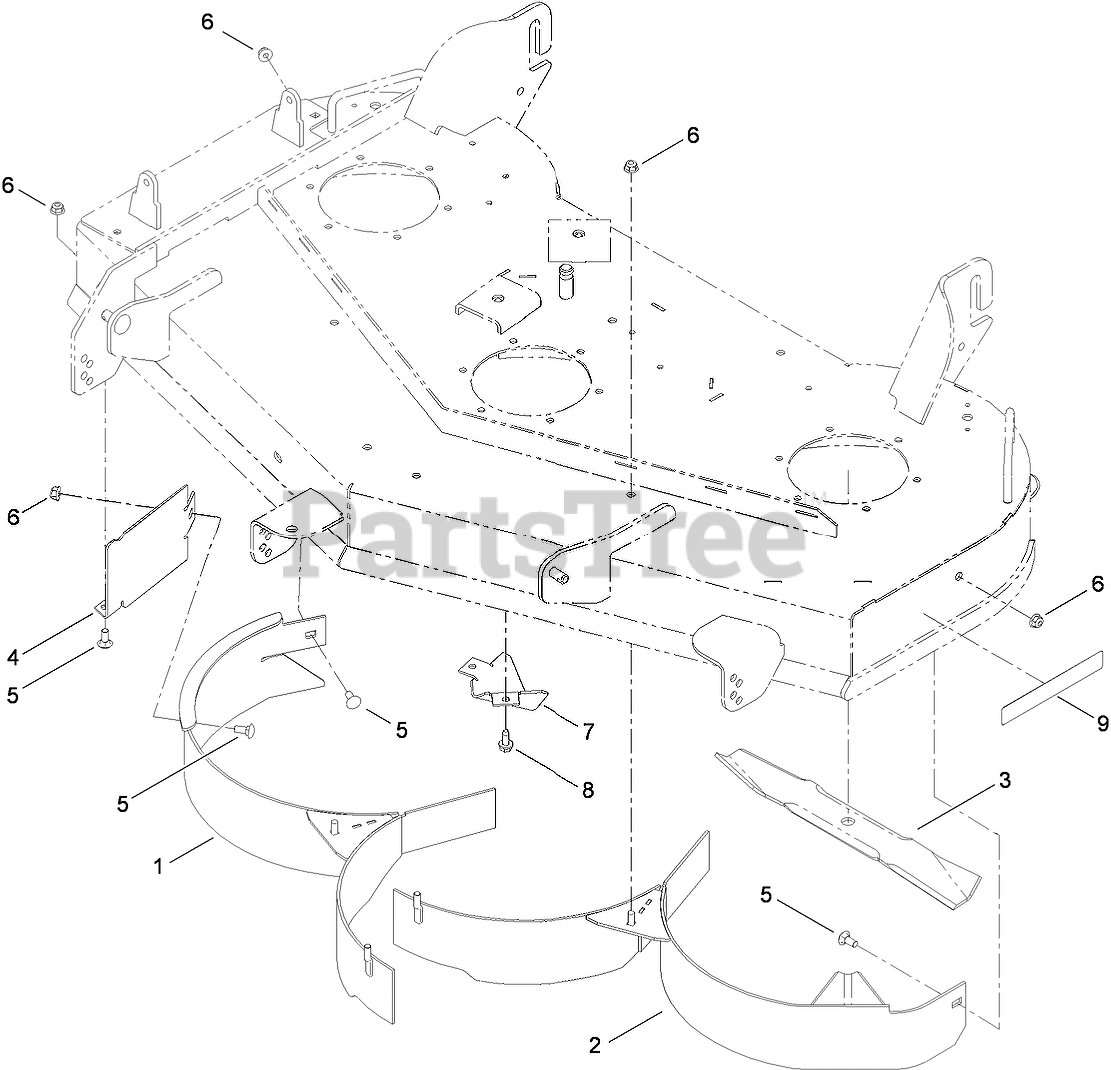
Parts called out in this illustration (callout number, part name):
1	RH BAFFLE ASM
2	LH BAFFLE ASM
3	BLADE-MULCH, 16.50 INCH
4	GUARD-BAFFLE
5	BOLT-CARR
6	NUT-HF, NI
7	KICKER-FLANGED
8	SCREW-HWHTF
9	DECAL-RECYCLER
